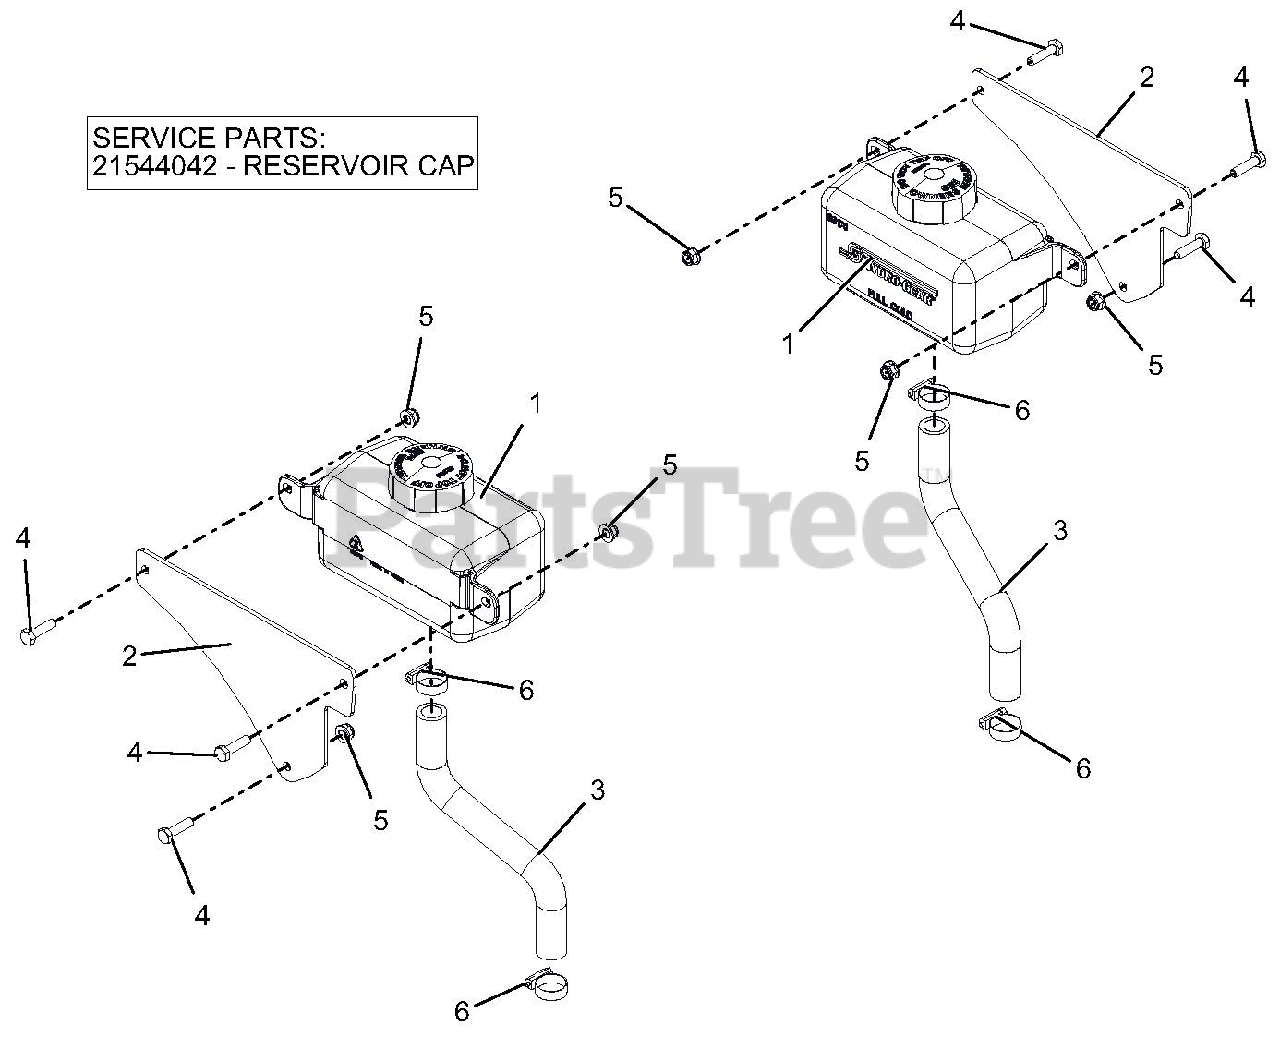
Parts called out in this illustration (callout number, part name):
1	TANK, HYD 1000ML
1	CAP, HYDRO RESERVOIR REPLAC.
2	HYDRO OVERFLOW TANK MTG PLT-RD
3	HOSE. HYDRO OVERFLOW
4	@BLT-HEX .25-20X1.00 GR5 YWZC
5	@NUT-LK-NYL-FLG .25-20 YWZC
6	CLAMP,.88 DIA. HOSE
